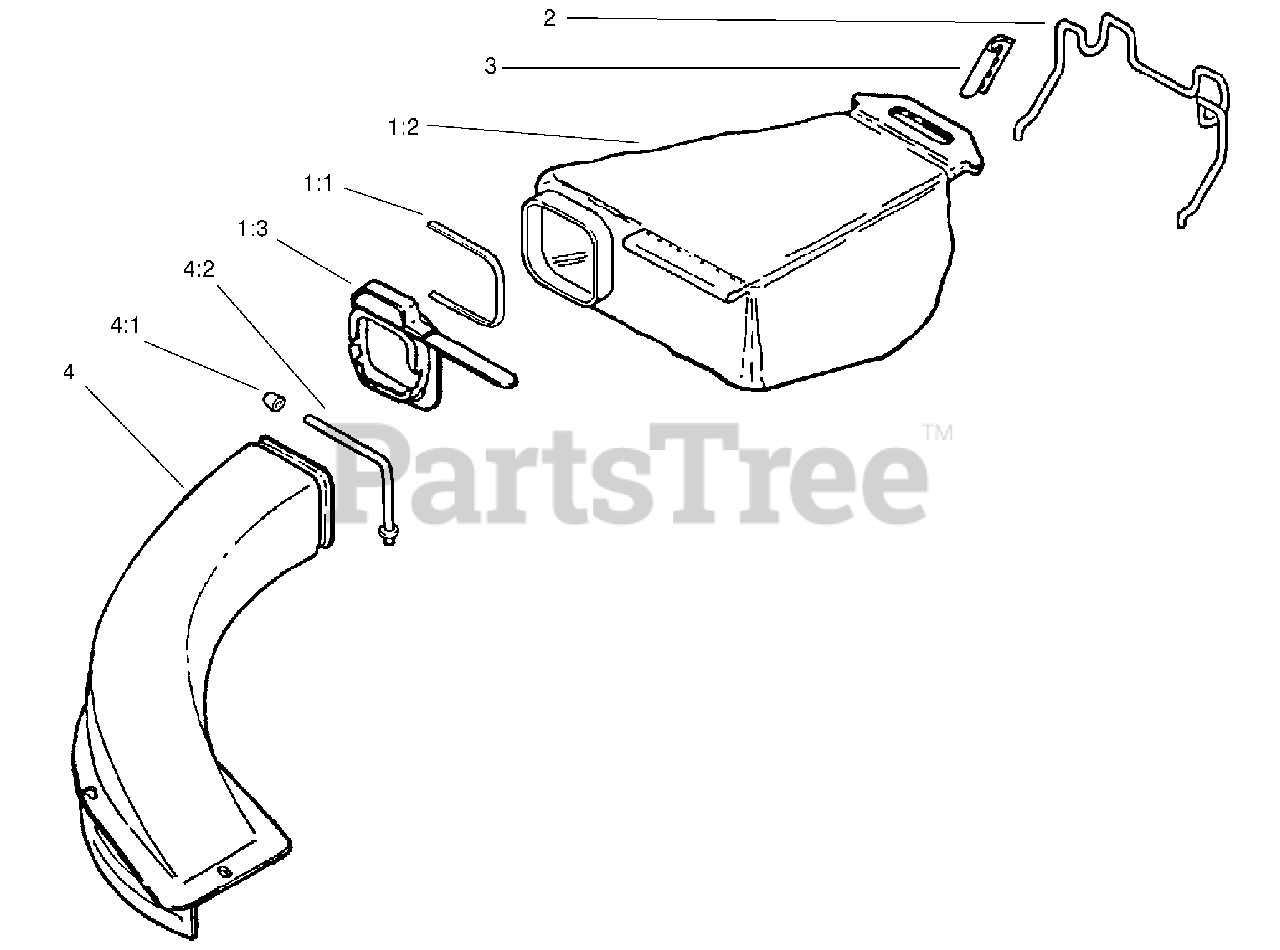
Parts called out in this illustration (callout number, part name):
1	BAG & ADAPTER ASM.
1:1	TIE STRAP
1:2	REPLACEMENT BAG ASM.
2	WIRE HANGER,
3	CLAMP-HANGER
4	CHUTE & SUPPORT
4:1	NUT - CAP
4:2	SUPPORT- CHUTE
